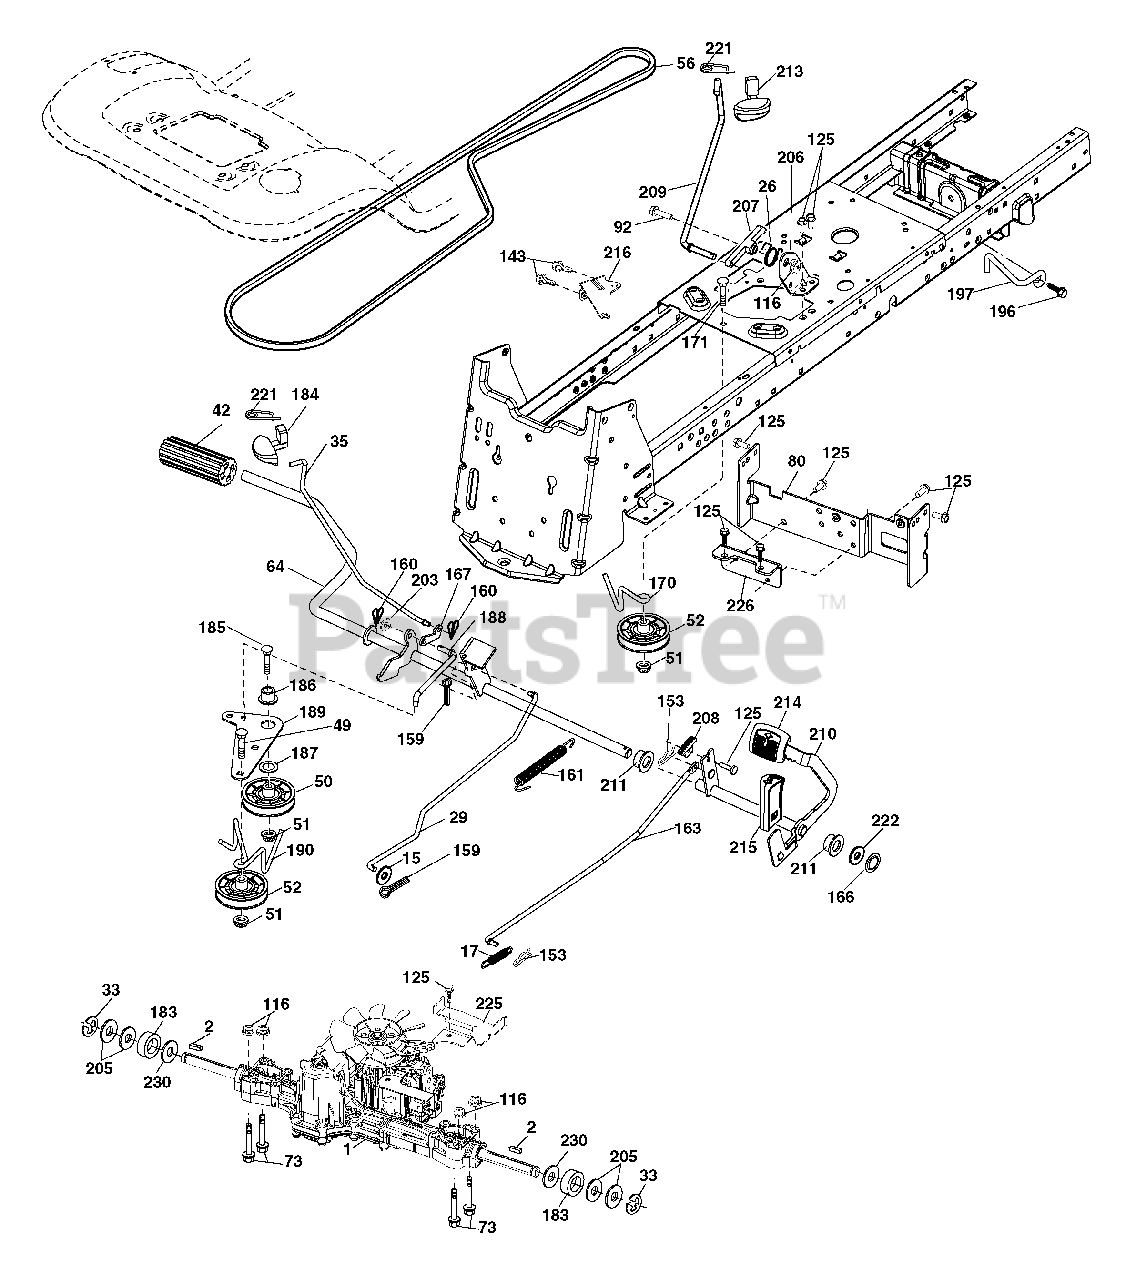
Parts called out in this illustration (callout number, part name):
1	Transaxle, TUFFTORQ K46
15	Washer 13/32 x 13/16 x 16 Ga.
17	Spring, Brake
26	Spring Return Cruise
29	Rod, Brake
35	Rod, Brake, Park
42	Cover, Foot Pedal
50	Pulley Idler Flat
51	Lock Nut 3/8-16
52	Idler V-Groove 910 Offset
56	V-Belt, Drive
64	Shaft Asm. Pedal Brake Control
73	Bolt Hex Flghd 5/16-18 Gr. 5
80	Bracket Strap Torque
92	Bolt Fin Hex 5/16-18 unc x 1.25
116	Nut Lock Hex Flange 5/16-18
125	Screw 5/16-18 x 3/4
143	Screw 5/16-18 x 1/2
153	Retainer Spring
159	Pin Cotter 1/8 x 3/4
160	Retainer Clip
161	Spring, Return, Clutch
163	Rod Pedal Control
166	Nut Push
167	Latch Brake Parking
170	Keeper Belt Centerspan
171	Bolt RDHD SQNK 3/8-16UNC x 2
183	Spacer Split
184	Handle Parking Brake
185	Bolt Rdhd Sqnk 3/8-16 x 2-1/2
186	Spacer Retainer
187	Washer
188	Link Clutch Ground Drive
189	Bellcrank Ground Drive
190	Keeper Bellcrank Ground Drive
196	Screw 3/8-16 x 1
197	Bracket Clutch Anti-Rotation
203	Washer 11/32 x 11/16 x 16 Ga.
206	Bracket Mount Latch Cruise
207	Latch Control Cruise
208	Gear Sector Control Cruise
209	Rod Control Cruise
210	Rocker Asm. Pedal Control
211	Bearing Nylon
213	Knob Control Cruise
214	Pedal Forward
215	Pedal Reverse
216	Bracket Pulley Idler
221	Retainer Spring Clip Handle
222	Washer 21/32 x 1-1/4 x 10 Ga.
225	Keeper Belt Trans.
226	Bracket Mount Touque
230	Washer Hardened
